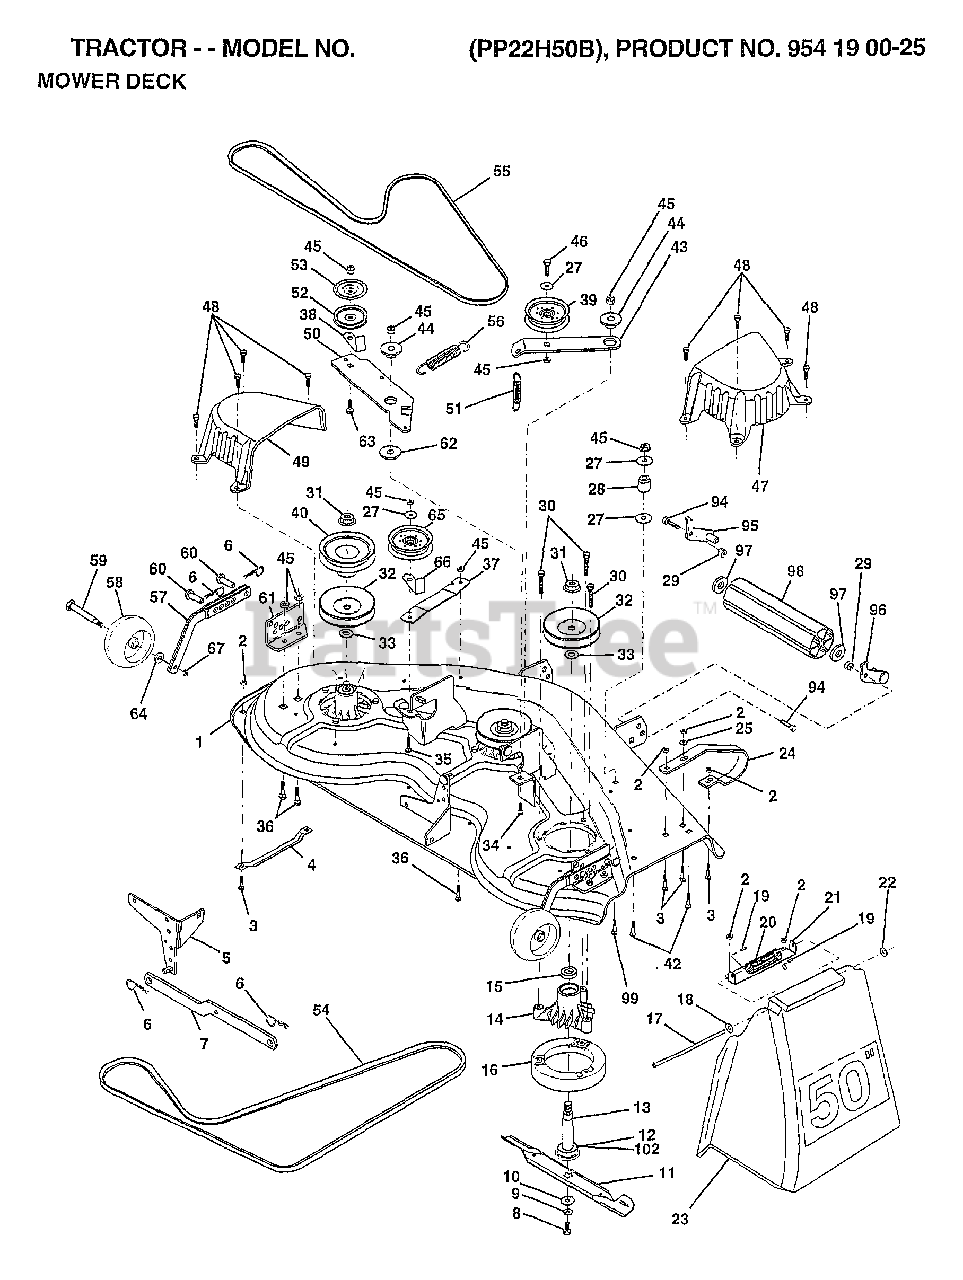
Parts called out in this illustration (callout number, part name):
1	"DECK ASM-50"""
4	RUNNER-LH M
5	BRKT.ASM.SW.44/50
8	BLADE BOLT
10	WASHER.HARD.BLADE
11	"BLADE.50"" HD"
12	BEARING.BALL
13	SHAFT.ASM.W/BRNG
14	HOUSING.MAND.44.V
15	BEARING
16	STRIPPER RND MWR
17	ROD-HINGE T
18	WASHER
19	CAP-SLEEVE LT
20	SPRING TORSION
21	BRKT DEFLECTOR
22	NUT PUSH M
23	DEFLECTOR
24	"RUNNER RH 50"" DK"
25	WASHER M
27	WASHER
29	NUT
30	"SCREW-THD ROLL,WA"
32	PULLEY.MANDREL.42
33	WASHER
34	BOLT.3/8-14X1.25
35	BOLT
36	BOLT D
37	STIFFENER.ARM.IDL
38	"KEEPER-BELT,IDLER"
39	FLAT IDLER PULLEY
40	"PULLEY.DRIVEN.44"""
42	BOLT
43	"ARM.IDLER.SEC.44"""
44	SPACER RETAINER
47	"COVER.MAND.RH.44"""
48	SCREW.1/4-20X5/8
49	COVER.MANDREL.LH
50	ARM.IDLER.PRIMARY
51	"SPRING.SEC.44""VEN"
52	PULLEY.IDLER.VGRO
53	SHIELD.IDLER.44.V
54	BELT V PRIM 50
55	BELT-V.SEC.46.KEL
56	SPRING.EXT.DECK.
57	BAR.ASM.GUAGE.WHL
58	WHEEL.GUAGE.MED.
59	BOLT.SHOULDER
60	PIN.CLEVIS
61	BRACKET.GUAGE.WHL
62	HARDENED WASHER
63	BOLT.3/8-16X1.50
64	WASHER
65	PULLEY IDELR FLAT
66	"KEEPER-BELT,IDLER"
67	LOCKNUT
94	BOLT
97	WASHER
99	BOLT
102	WASHER.FELT.
